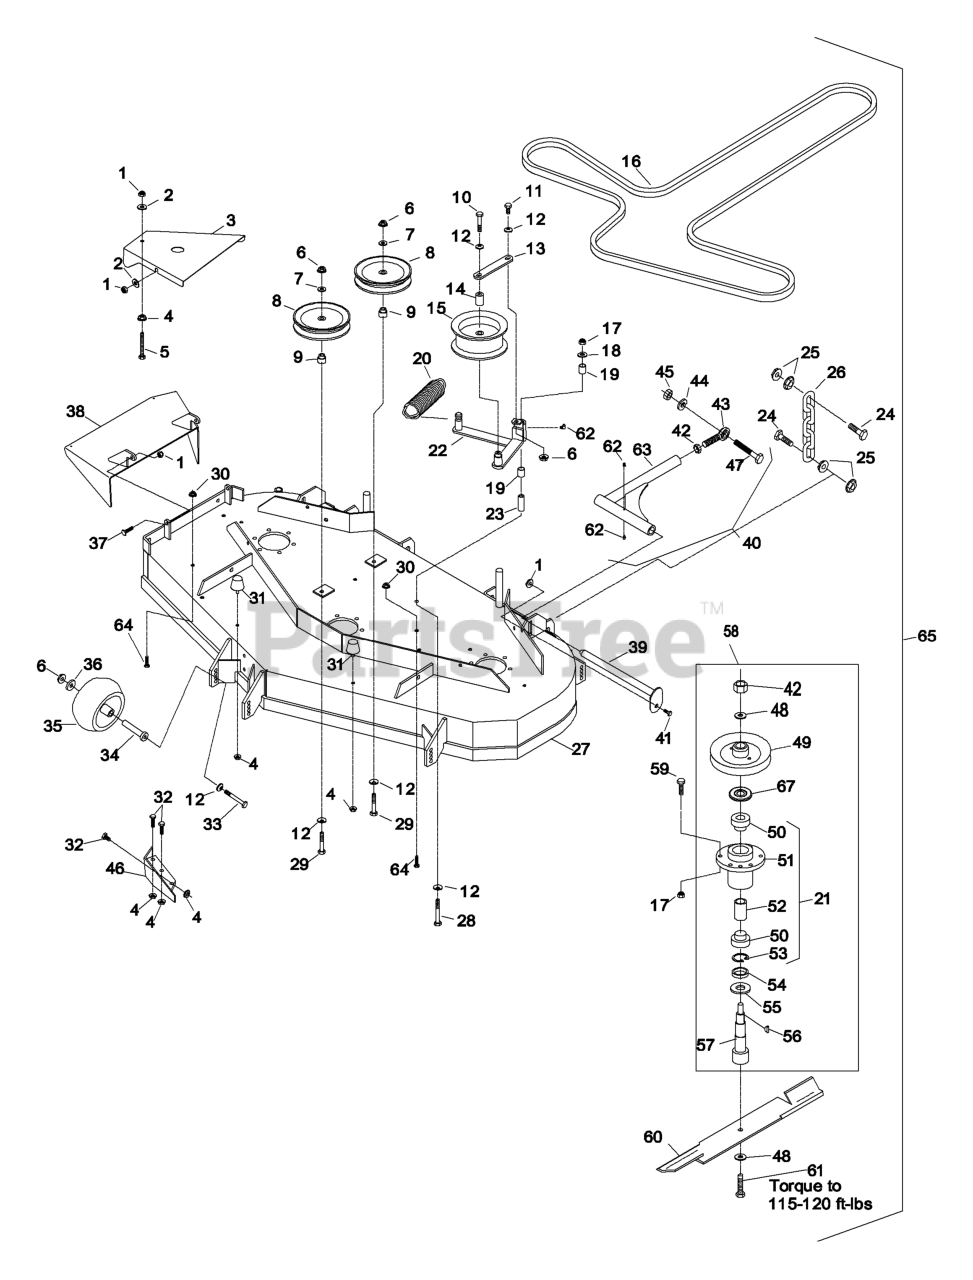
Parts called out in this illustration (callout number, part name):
1	NUT-LOCK, NI
2	WASHER-FLAT
5	BOLT,TAP HH
6	NUT-HHF, WHIZ
7	WASHER-FLAT
8	PULLEY-IDLER
9	BUSHING-IDLER
10	SCREW-HH
11	SCREW-HH
12	WASHER-BELLEVILLE
16	BELT,BLADE DRIVE
17	NUT-LOCK, NI
18	WASHER-FLAT
19	SLEEVE-BEARING
23	BUSHING-PIVOT, IDLER
24	SCREW-CAP, HH
26	CHAIN-LIFT, DECK
28	SCREW-HH
29	SCREW-HH
31	BUMPER-RUBBER
32	SCREW-HH
33	SCREW-HH
34	BUSHING-ROLLER
35	ROLLER-SCALP, ANTI
37	SCREW-HH
38	WLD,DISCHARGE CHUTE
39	PIN-STRUT
40	STRUT ASM
41	SCREW-HH
42	NUT-HEX
43	BALLJOINT-SPHERICAL
44	WASHER-LOCK
45	NUT-HEX
46	WLD,BAFFLE DISCHARGE
48	WASHER-SPRING
49	SHEAVE,6.13 EOD
50	BEARING
52	SPACER-BEARING
54	SPACER-PULLEY/BEARING
55	GUARD-BEARING, BOTTOM
56	KEY-RECTANGLE
57	SHAFT,SPINDLE
58	ASM,CUTTER HSG SERVICE
59	SCREW-HH
61	SCREW-CAP
62	FITTING-GREASE
64	SCREW-HH
65	Deck Complete Service
66	WASHER-BLADE BOLT, HEAVY
67	GUARD-BEARING, TOP
